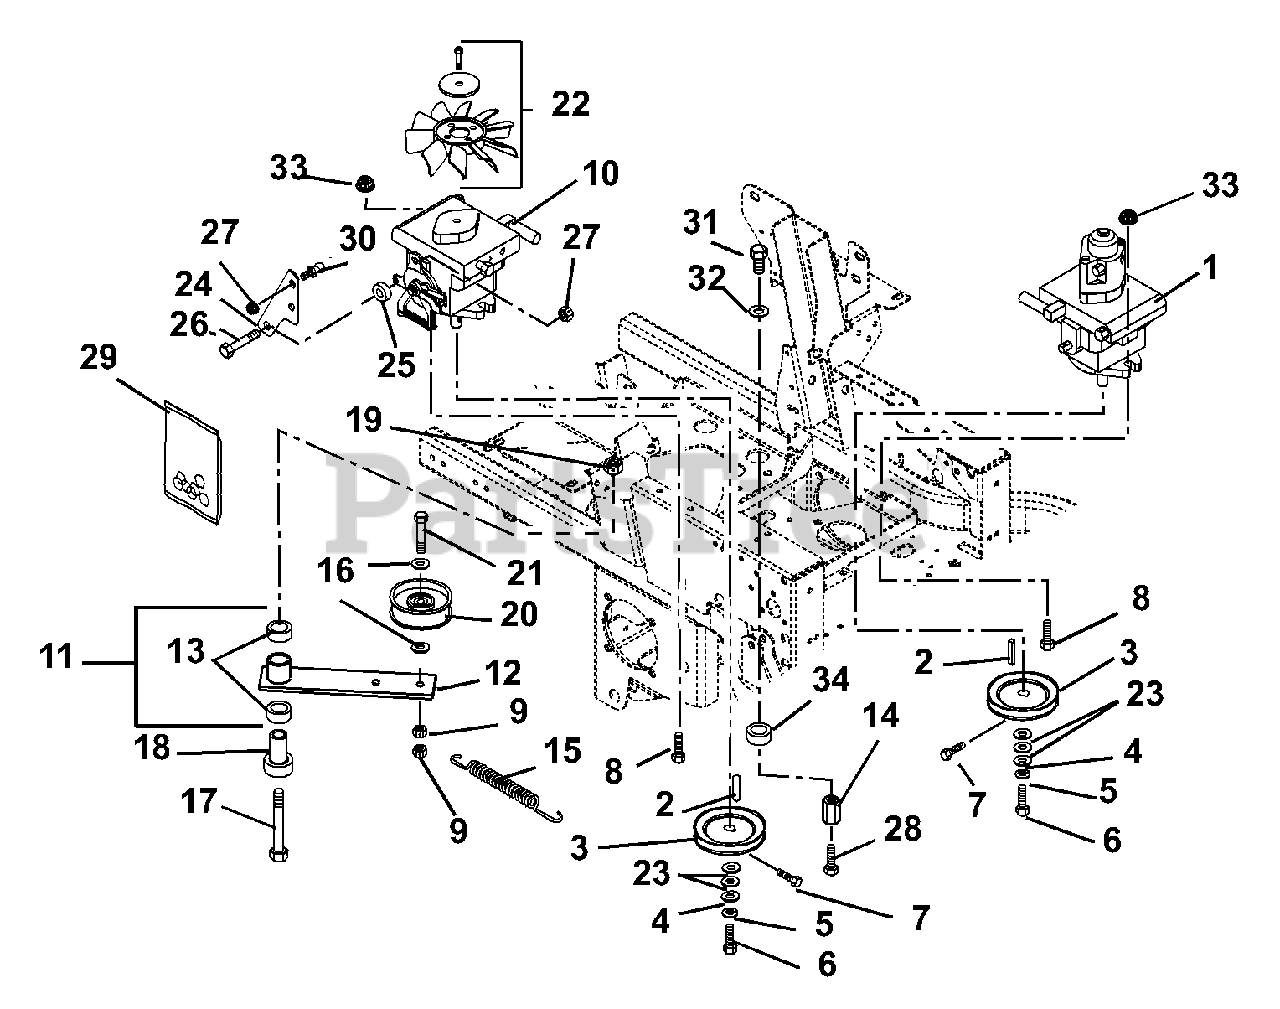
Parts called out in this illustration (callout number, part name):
1	Pump, Hydraulic BDP-10A Left Hand
2	Key, Straight 5mm x 25mm x 5mm
3	Sheave, 4.0 x .199
4	Washer, Flat Steel .281 x 1.00 x .063
5	Washer, Locking .25 x .062
6	Bolt, Hex M6 x 1.0 x 12
7	Bolt, Hex .25-20 x .50 Grade 5
8	Bolt-Round Head Square Neck .44-14 x 1.50 Grade 5
9	Nut, Locking Top Flange .38-16
10	Pump, Hydraulic
11	Assembly, Idler Arm Guard Drive
12	Weldment, Idler Arm Ground Drive
13	Bearing, 1.00 x 1.12 x .75
14	Nut Coupling .375-16 x 1.75
15	Spring, Tension .120 x .845 x 6.50
16	Washer, Flat Steel .39 x.75 x.125
17	Bolt, Hex .50-13 x 3.50 Grade 5
18	Bearing, Pedestal
19	Nut, Locking Top Flange .50-13
20	Idler-Flat 4.00 x .38
21	Bolt, Hex .38-16 x 2.25 Grade 5
22	Fan, Cooling
23	Washer, Flat Steel .656 x 1.31 x .095
24	Bracket, Return to Neutral/Damper
25	Spacer .344 x 1.00 x .375
26	Bolt, Hex .31-18 x 1.25 Grade 5
27	Nut, Locking Top Flange .31-18
28	Bolt-Hex .38-16 x 1.50 Grade 5
29	Kit, Pump Seal
30	Stud, Ball
31	Bolt-Hex .38-16 x 1.00 Grade 5
32	Washer, Locking .38 x .094
33	Nut-Nyloc Flange .44-14
34	Bushing-Sleeve .377 x .624 x .370
